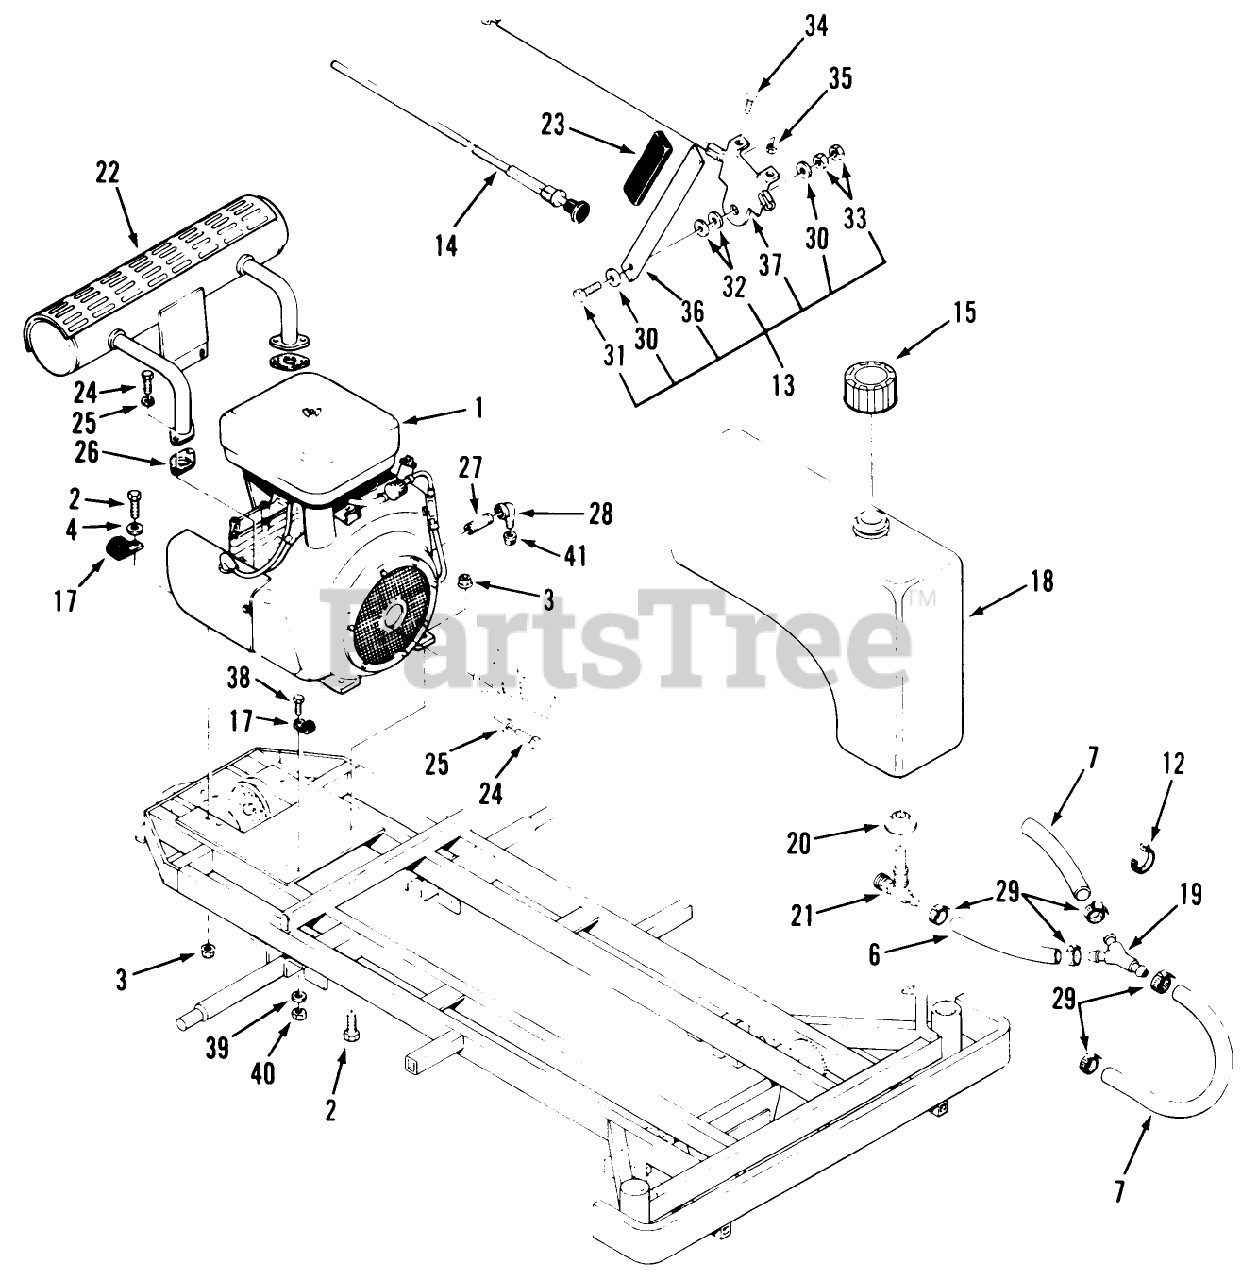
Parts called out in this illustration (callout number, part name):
1	Tire-Turf Tray, Front 12 X 7.5-8
2	BOLT
3	NUT
4	Washer
6	Hose5"
7	Fuel Line (29.5")
12	TIE-PLASTIC
13	Throttle Control (Includes items 30 thru 33, 36 & 37)
14	CABLE-CHOKE
15	GAS CAP ASM
17	CLIP
18	Fuel Tank (Includes items 20 & 21)
19	FITTING-FUEL 45-Y
20	BUSHING
21	VALVE-FUEL
22	MUFFLER
23	GRIP BRAKE20258-K
24	Bolt
25	Lockwasher
26	Exhaust Gasket
27	Pipe
28	STREET-ELBOW 90 DEG
29	Clamp
30	SPRING-BELLEVILLE
31	HHCS
32	WASHER NYLON
33	LOCKNUT 5/16-18GR.B
34	Screw-Machine
35	Nut
36	HANDLE-THROTTLE B
37	CABLE-THROTTLE
38	Bolt
39	WASHER 5/16 SAE
40	Nut
41	Cap
42	Manual-Toro Power Plus Service
